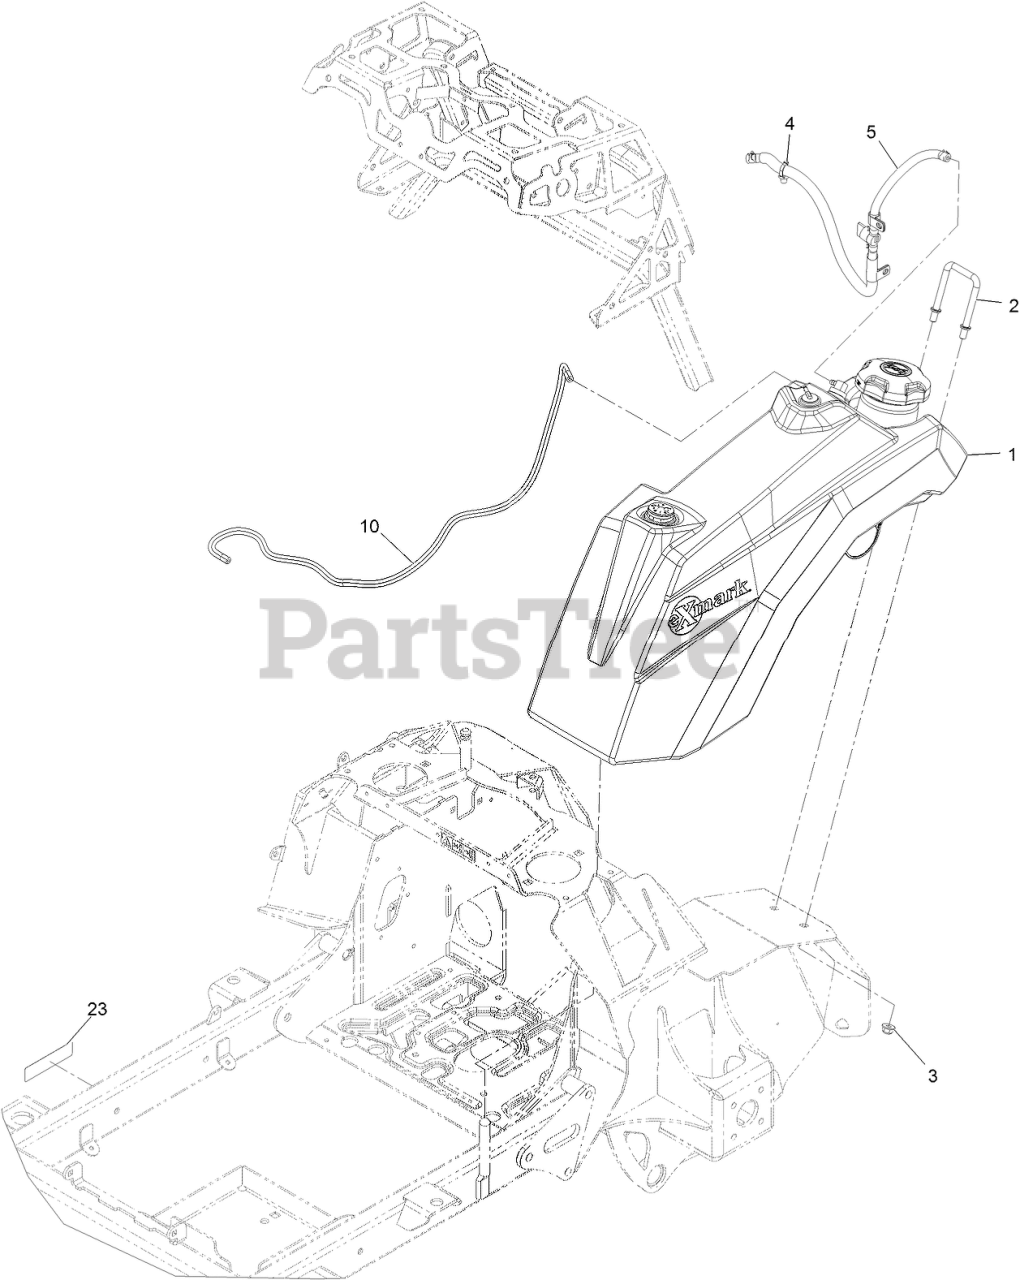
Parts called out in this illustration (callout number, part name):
1	ASSEMBLY, FUEL TANK
2	CLAMP, TANK
3	NUT-HF, NI
4	CLIP-TIE
5	ASM-Fuel Line & Valve
10	HOSE-FUEL
23	DECAL-ARRESTOR, SPARK
